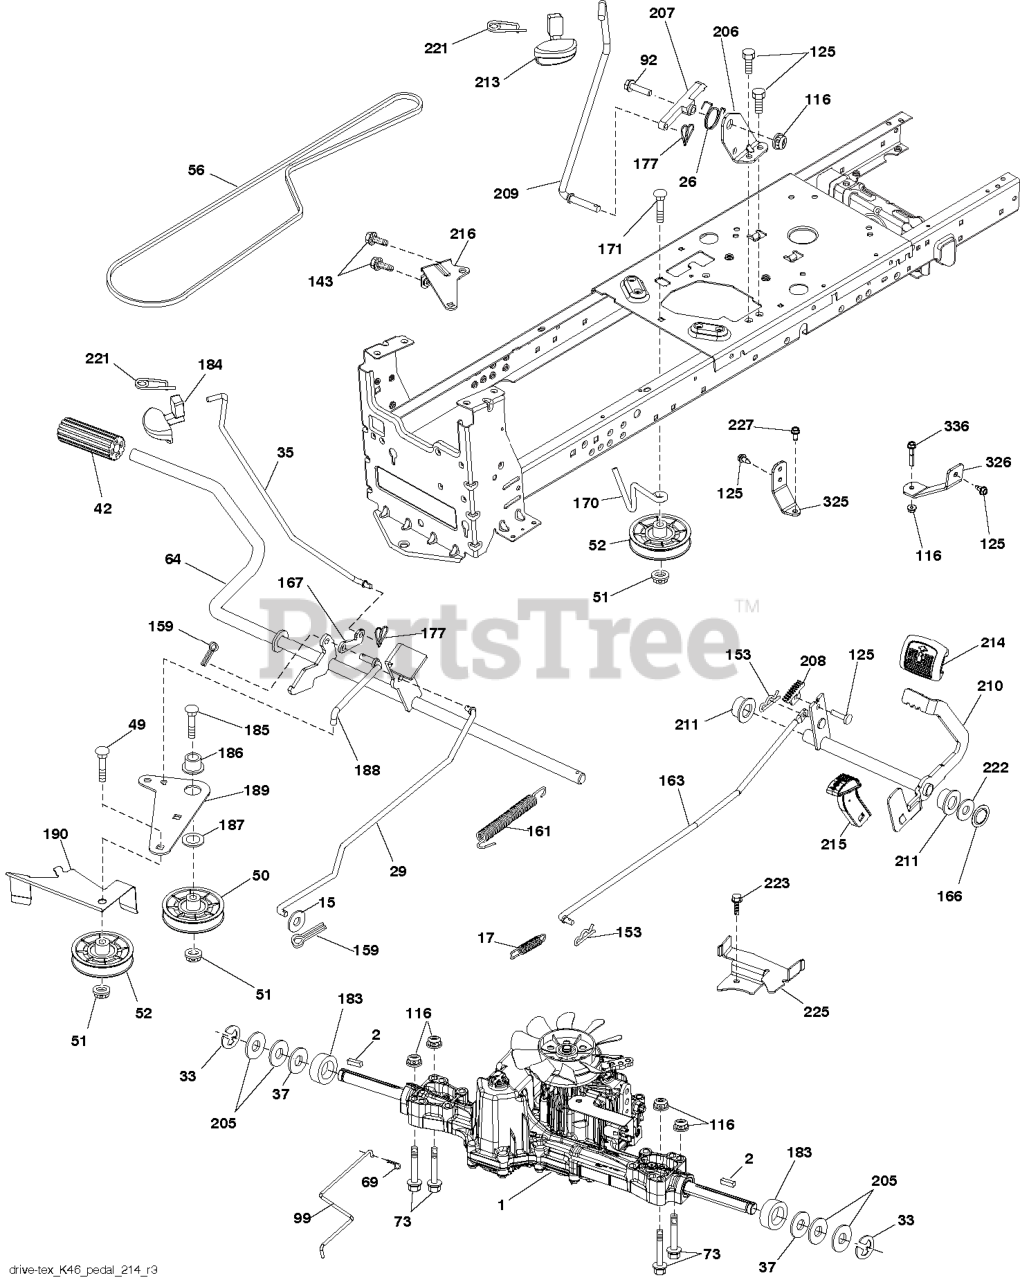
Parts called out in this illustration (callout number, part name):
2	SQUARE KEY
15	WASHER
15	WASHER PLAIN WASHER 3/8 X 0.08
17	SPRING.BRAKE.K46.GREEN
26	SPRING.RETURN.CRUISE
29	ROD.BRAKE.K46
35	ROD ROD.PARKINGBRAKE.GT.HUSQ/P
37	WASHER.HARDENED
42	PEDAL COVER
49	BOLT
49	Bolts
50	IDLER.FLAT.910.OFFSET
51	NUT LOCK FLG 3/8-16 UNC
52	IDLER.V-GROOVE.910.OFFSET
64	SHAFT.ASM.PEDAL.BRK.CNTR
69	HAIRPIN.SOFT.ZINC.059X1.125
99	ARM.PIVOTING.TCRD.GEN2.5.BAGGE
116	NUT LOCK HEX FLANGE 5/16-18
116	GSPW Nuts
125	SCREW
143	Screws
143	SCR 5/16-18 X 1/2 SELFTAP ZN
153	RETAINER M
161	SPRING, RETURN LT
166	NUT.PUSH.625
167	LATCH.BRAKE.SPRING
170	KEEPER.V-IDLER.CENTER.
177	RETAINER CLIP
177	PIN COTTER;LOCKING;BOWTIE;1IN
177	GSPW Retainers
183	SPACER AXLE
184	HANDLE.PARKING.BRAKE.H (BLK)
186	SPACER.RETAINER
188	LINK.CLUTCH.GROUND DRIVE.LONG
189	BELLCRANK.GROUND.DRIVE.TEX.
190	KEEPER.BELLCRANK.DRIVE
206	BRACKET.MOUNT.CRUISE.LATCH
209	ROD ROD.CRUISECONTROL.GT.HUSQ/
210	ROCKER.ASM.PEDAL.CONTR
211	BEARING.NYLON
213	KNOB.CONTROL.CRUSIE.HU
214	PEDAL.FORWARD.PAD.TEX
215	PEDAL.COVER.REVERSE.CRD.X428BK
216	BRACKET.PULLEY.IDLER.W/TEX
221	RETAINER.SPRING.CLIP.H
222	WASHER 21/32 X 1-1/4 X 10 GA.
225	KEEPER.BELT.TRANSAXLE.K46
227	SCREW.THDROL.5/16-18X3/4.TTY
227	Bolts
325	BRACKET.TRQ.STP.46.20".TIRE.LH
326	BRCKT.PNT.TRQ.STP.46.20TIRE.RH
